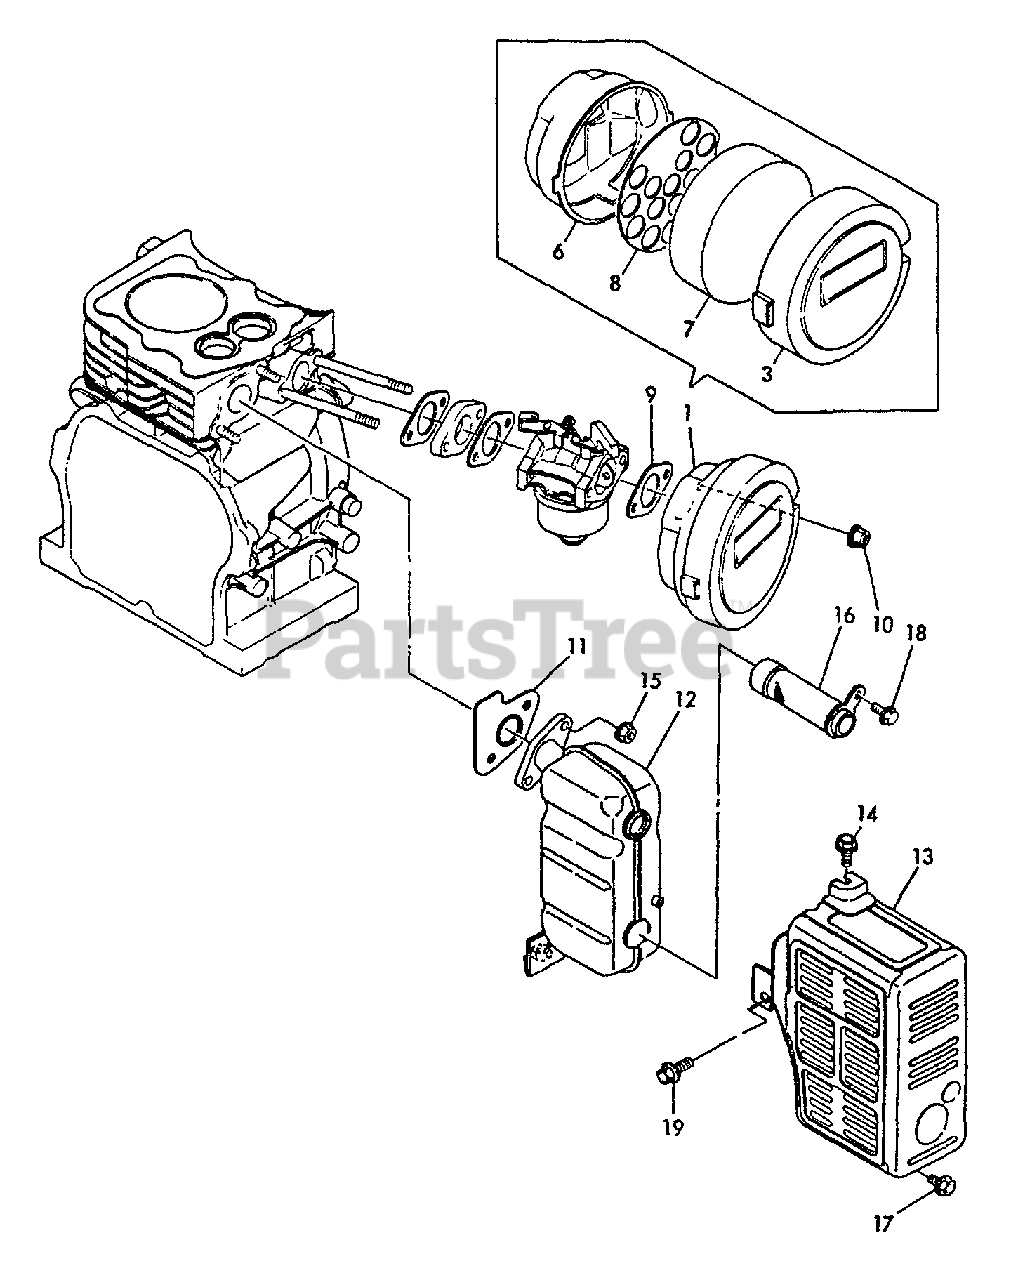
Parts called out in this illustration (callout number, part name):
1	CLEANER ASSY, AIR
3	COVER, AIR FILTER
6	CASE, AIR FILTER
7	FILTER, AIR
8	HOLDER, ELEMENT
9	GASKET, INTAKE
10	U-NUT M6
11	GASKET, EXHAUST
12	MUFFLER
13	COVER, MUFFLER
14	BOLT - 6×8 -- PLATED
15	U-NUT M6
16	SCREEN, SPARK ARRESTER
17	BOLT - 6×8 -- PLATED
18	BOLT - 6×10 -- PLATED
19	BOLT - 8×14 -- PLATED
